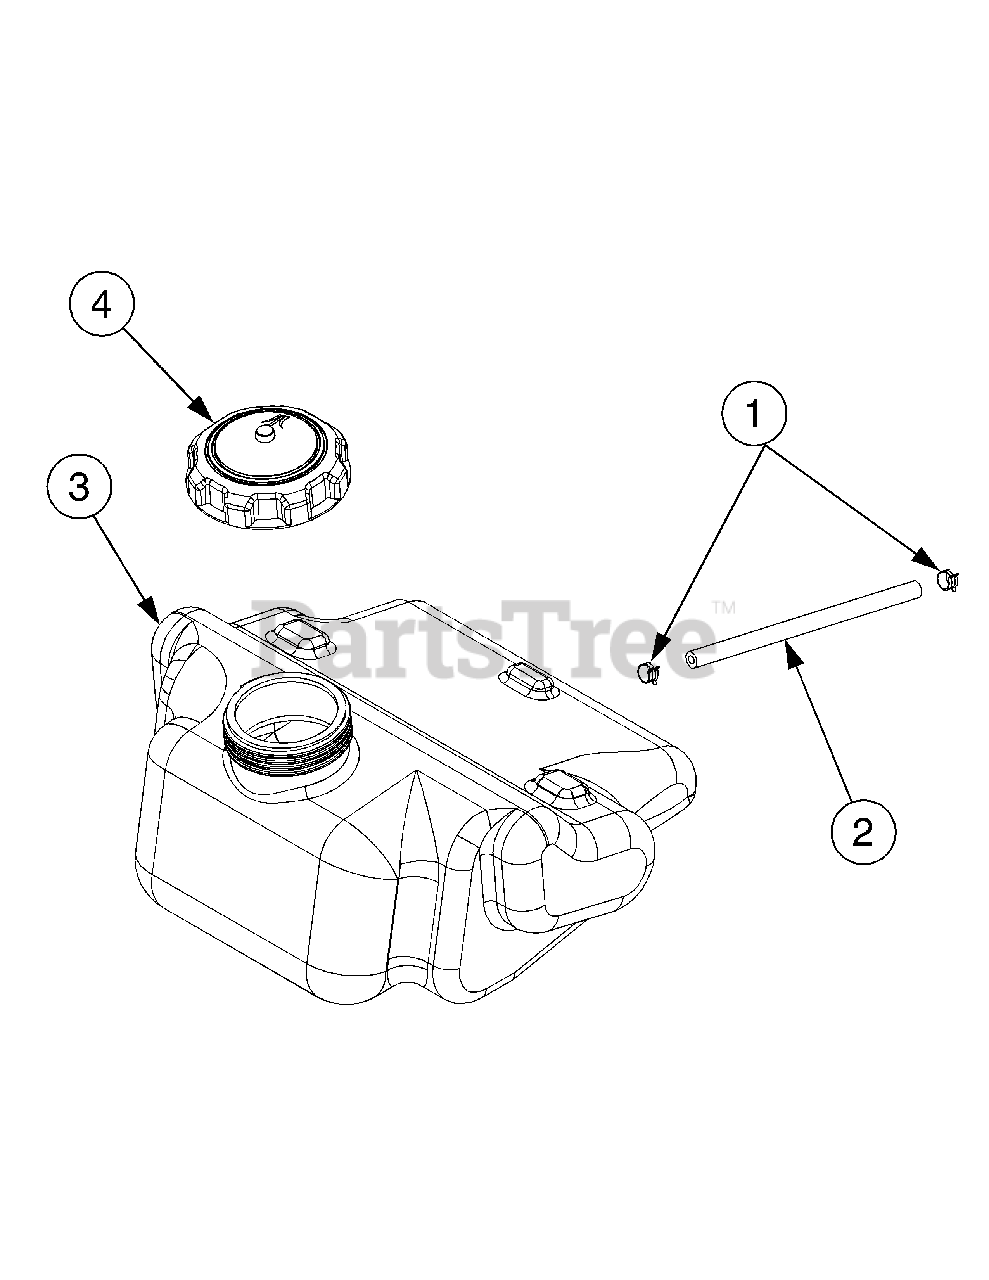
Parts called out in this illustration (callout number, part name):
1	Clamp, Hose
2	Line, Fuel, 72"
3	Tank, Fuel
4	Cap, Fuel
